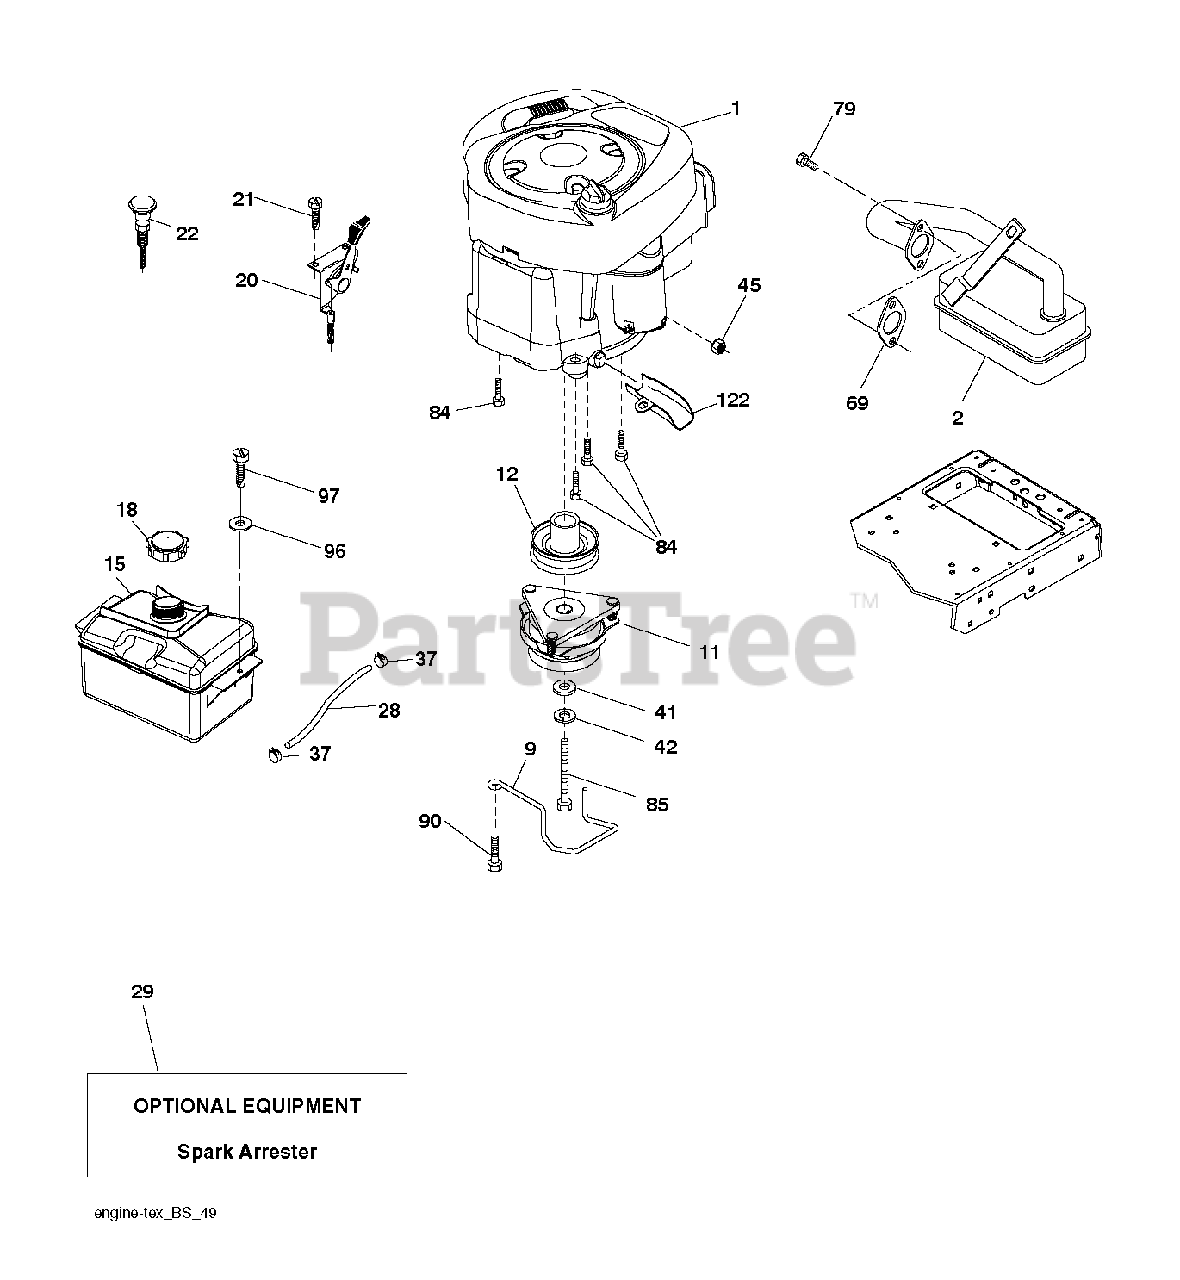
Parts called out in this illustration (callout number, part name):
9	KEEPER.BELT.ENGINE.4.2
11	CLUTCH.ELECTRIC.LT.48"*
12	PULLEY.ENGINE.TUFFTORQ
15	TANK FUEL FRT 1.5 GAL
18	CAP ASM.FUEL.2.25"FR.
20	CONTROL.THCK.COBRA.BS
21	SCREW.#10 X 0.750.BOS THREAD
22	CONTROL.CHOKE.ERGO.1CYL.30".YE
29	ARRESTER SPARK (OPTIONAL)
42	LOCKWASHER
45	NUT
69	REPL BY 532 27 22-93
79	SCREW.SOCKET HD.5/16-1
85	BOLT HEX 7/16-20X4-1/4"
90	SCREW 3/8-16X1
97	SCREW HEXWSHR 1/4-20X3/4
122	EXTENSION DRAIN OIL
